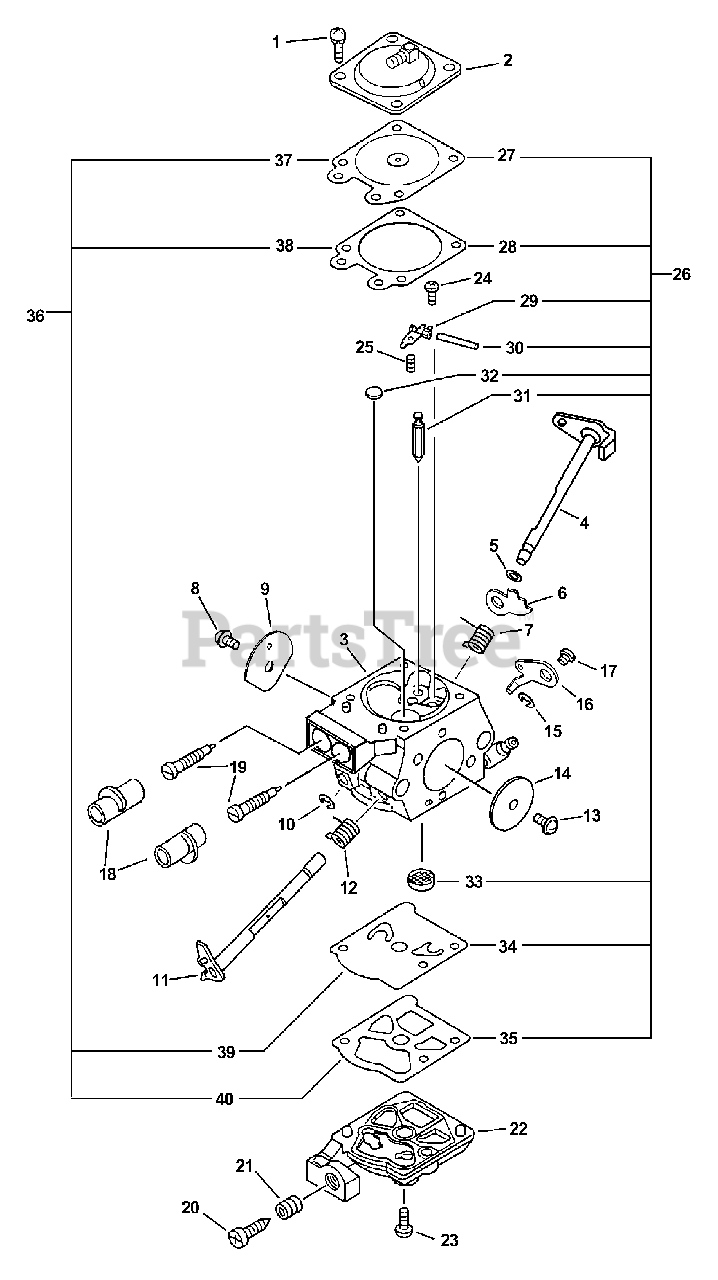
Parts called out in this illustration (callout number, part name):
2	COVER, DIAPHRAGM
3	BODY, CARBURETOR
4	SHAFT, CHOKE
6	LEVER, FAST IDLE
7	SPRING, CHOKE RETURN
9	VALVE, CHOKE
10	RING, RETAINING
11	SHAFT, THROTTLE
12	SPRING, THROTTLE RETURN
14	VALVE, THROTTLE
15	RING, RETAINING
16	LEVER, THROTTLE
18	CAP, LIMITER
19	NEEDLE - MIXTURE
20	SCREW, IDLE ADJUST
21	SPRING, IDLE ADJUST
22	COVER, FUEL PUMP
23	SCREW, PUMP COVER
24	SCREW, METERING LEVER PIN
25	SPRING, METERING LEVER
26	REPAIR KIT
27	DIAPHRAGM, METERING
28	GASKET, DIAPHRAGM
29	LEVER, METERING
30	PIN, METERING LEVER
31	VALVE, INLET NEEDLE
32	PLUG, WELCH
33	STRAINER
34	DIAPHRAGM, PUMP
35	GASKET, PUMP
36	DIAPHRAGM/GASKET KIT
37	DIAPHRAGM, METERING
38	GASKET, DIAPHRAGM
39	DIAPHRAGM, PUMP
40	GASKET, PUMP
